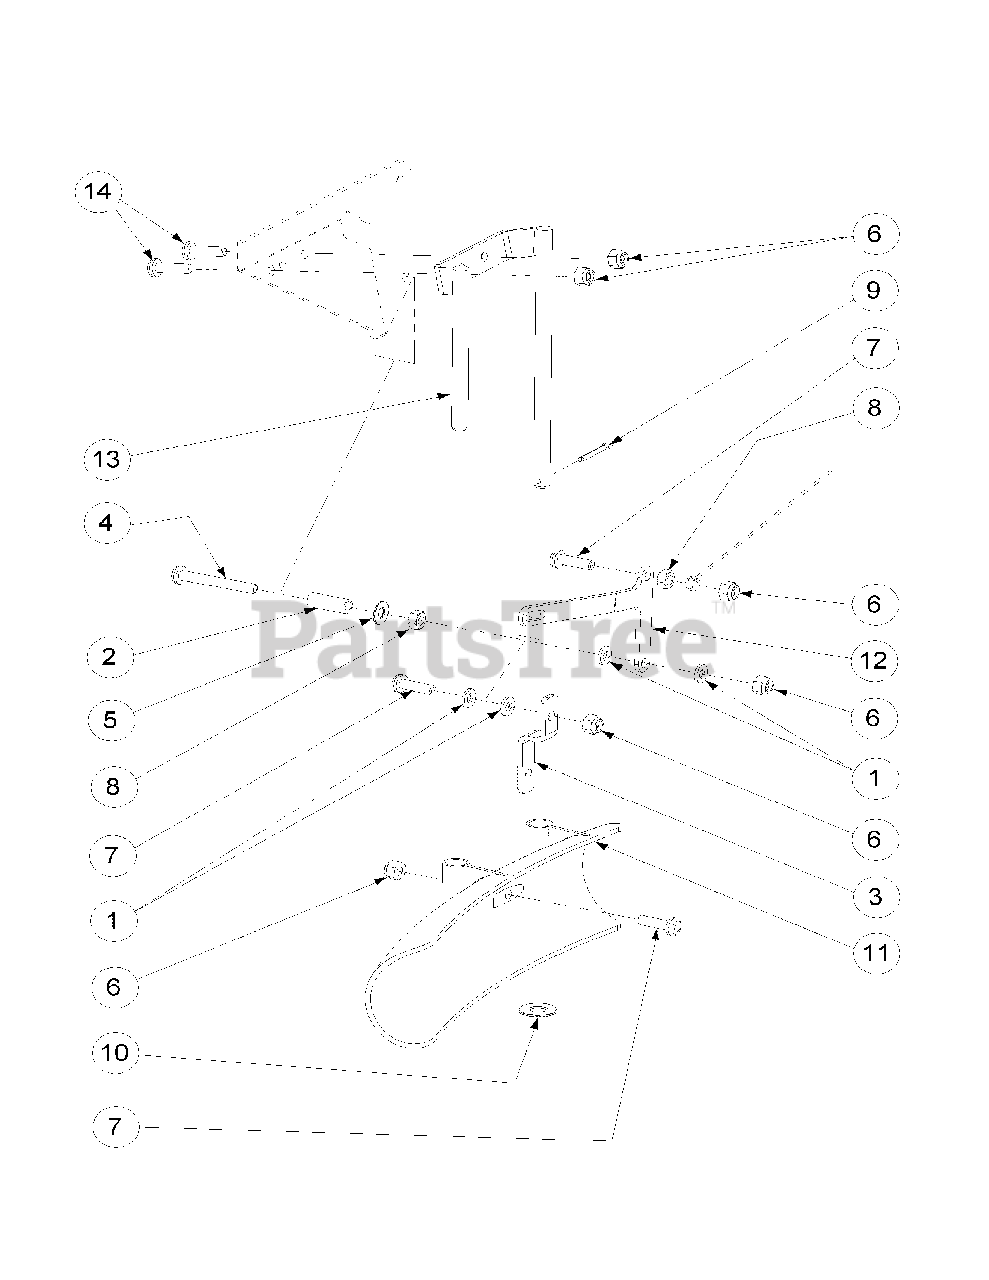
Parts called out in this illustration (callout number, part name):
1	Washer, 1/4
2	Deflector Arm Spacer
3	Offset Deflector Bracket
4	Machine Screw, 1/4-20 x 2
5	Washer, 1/4, SS
6	Nut, 1/4, SS
7	Machine Screw, 1/4-20 x 7/8
8	Nut, 1/4-20
9	Cotter Pin, 1/8 x 1, SS
10	Washer, 3/8, SS
11	Deflector Tube
12	Deflector Mount Lever
13	Deflector Mount Weldment
14	Socket Head Screw, 1/4-20 x 7/8
